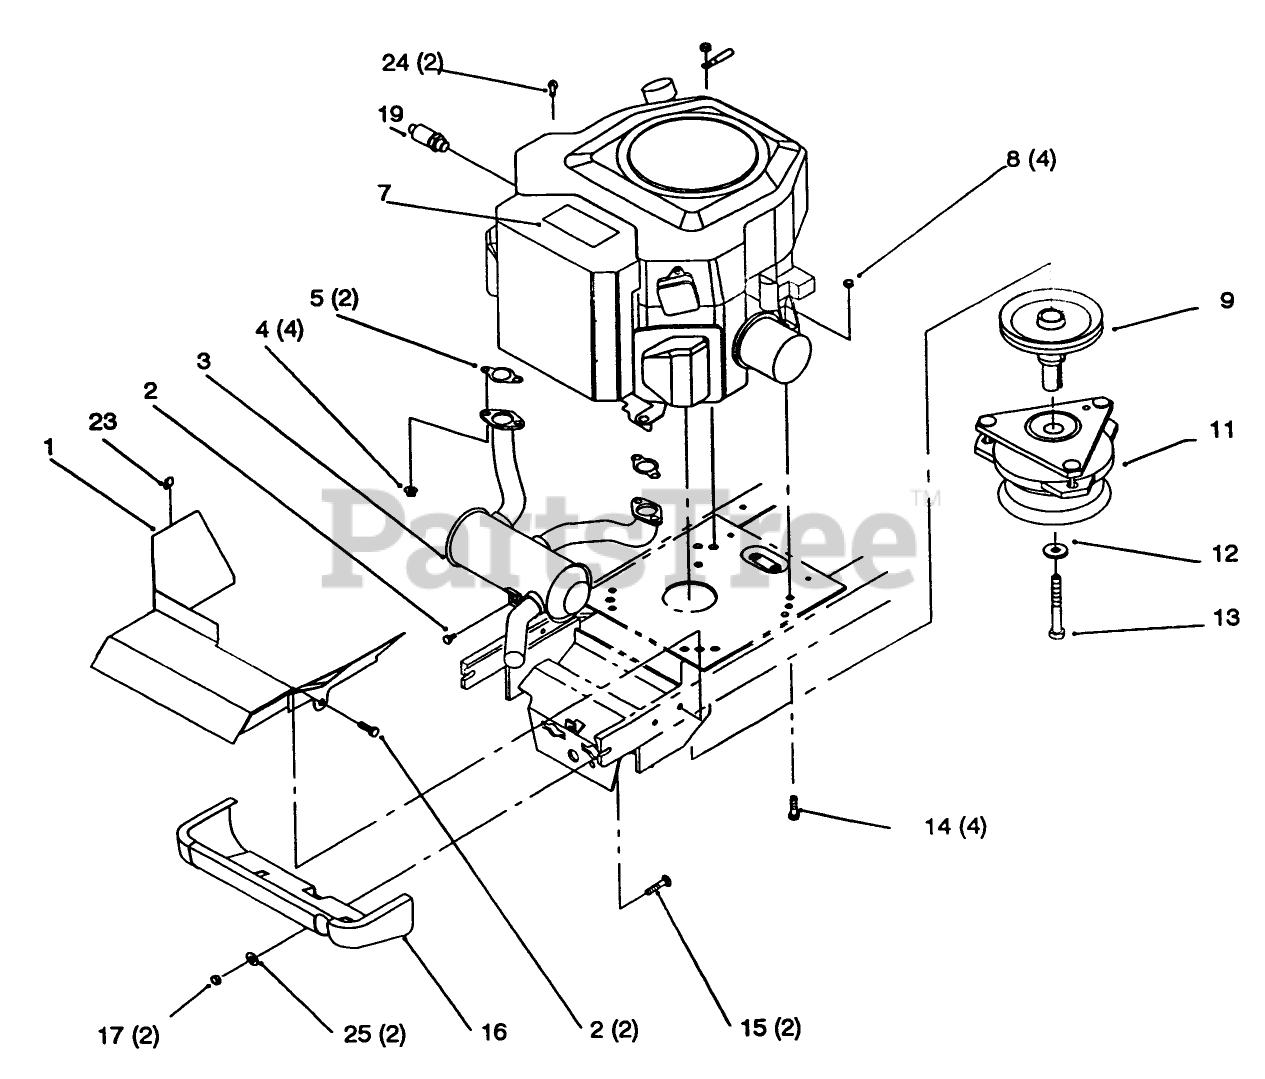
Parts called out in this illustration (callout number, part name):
2	Screw-HWHTF (Only On: 72103, 72083)
7	DECAL - ENGINE
8	NUT-LOCK, NI
9	PULLEY-ENGINE
11	CLUTCH - ELEC PTO
12	WASHER
13	SCREW-HH
14	SCREW-HH
15	SCREW-CARR
17	NUT-LOCK, NI
19	VALVE-DRAIN, OIL
23	CLIP-RETAINER, WIRE
24	SCREW-PPH
25	WASHER-FLAT
